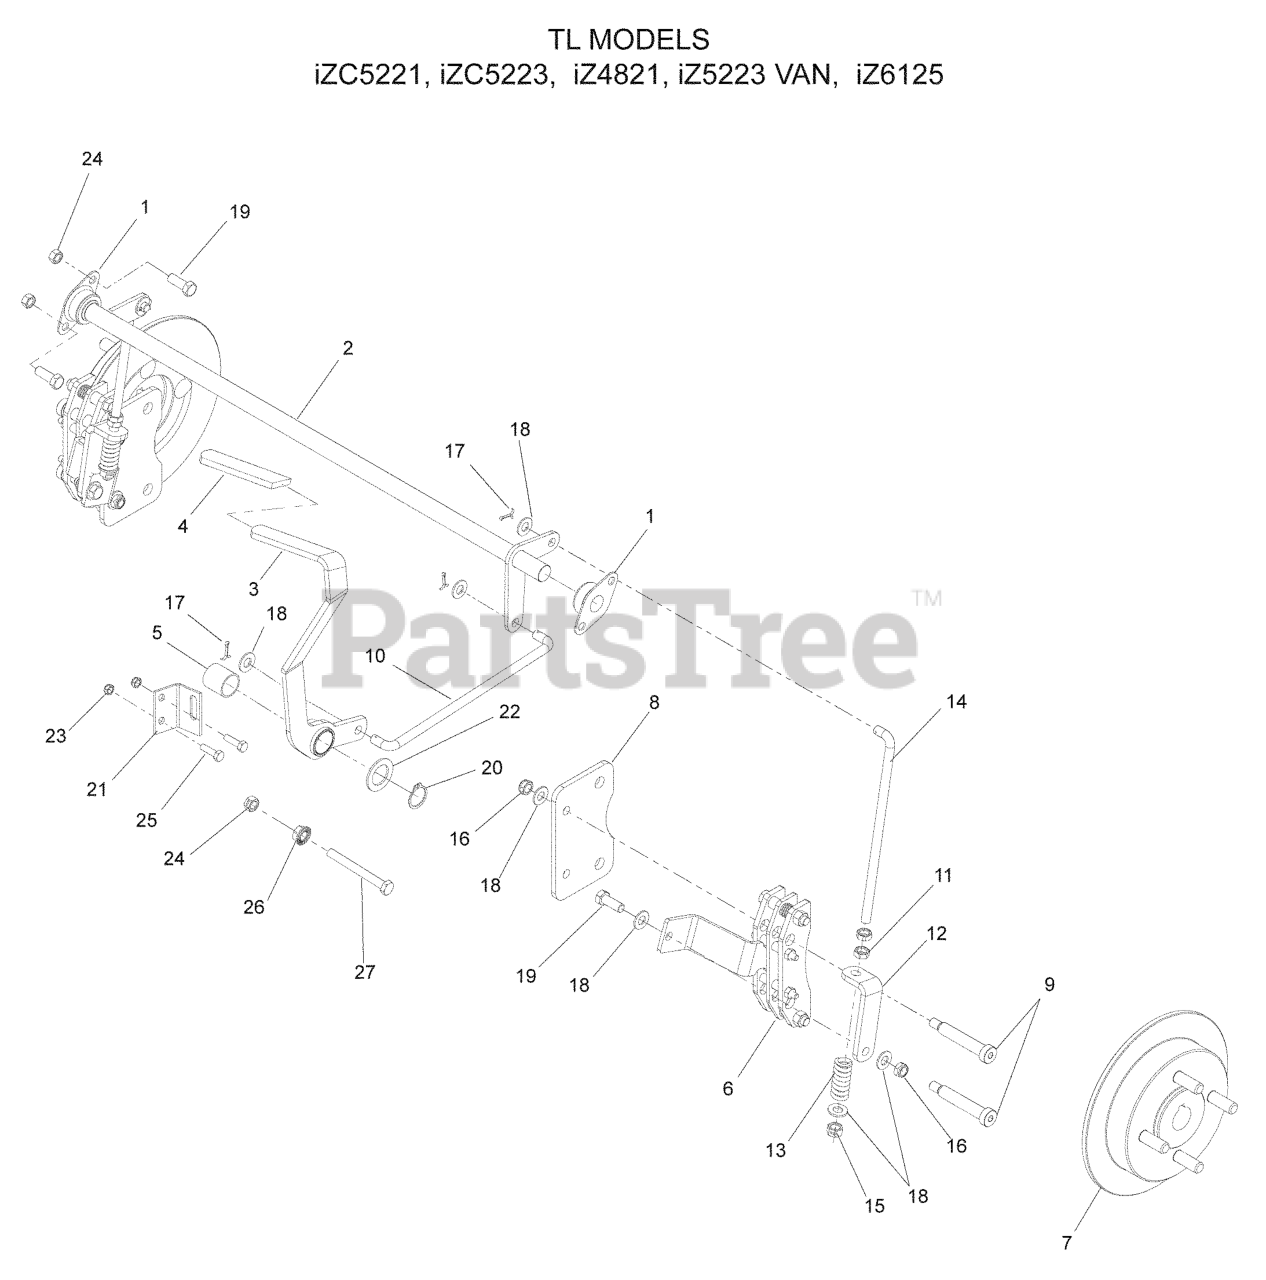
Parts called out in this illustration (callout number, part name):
1	FLANGE BEARING
2	BRAKE CROSS SHAFT
3	BRAKE LEVER WLDMT
4	GRIP, PARK BRAKE
8	PLATE, BRAKE
9	SB 3/8-16 X 2-1-1/2 SKT HDD ZD
10	LINKAGE, BRAKE
11	NUT 3/8-24 JAM
12	BRACKET, L
14	LINKAGE, REAR BRAKE
15	NUT 3/8F CENTERLOCK
16	NUT HEX 3/8-16 NYLON, THIN
17	COTTER PIN 3/32 X 3/4
18	WASHER 3/8 SAE FLAT
19	HCS 3/8-16X1.GRD.5.ZD
20	RETAINING RING, 7/8"
21	BRACKET, BRAKE SWITCH
22	BSHG .875 X 1.375 X .074 ZD
23	NUT.1/4-20.HEX.NYLOC.ZD
24	NUT 3/8-16 NYLOC
25	HCS 1/4C X 3/4 HCS
26	NUT 3/8C WHIZ
27	HCS 3/8C X 2 1/2
